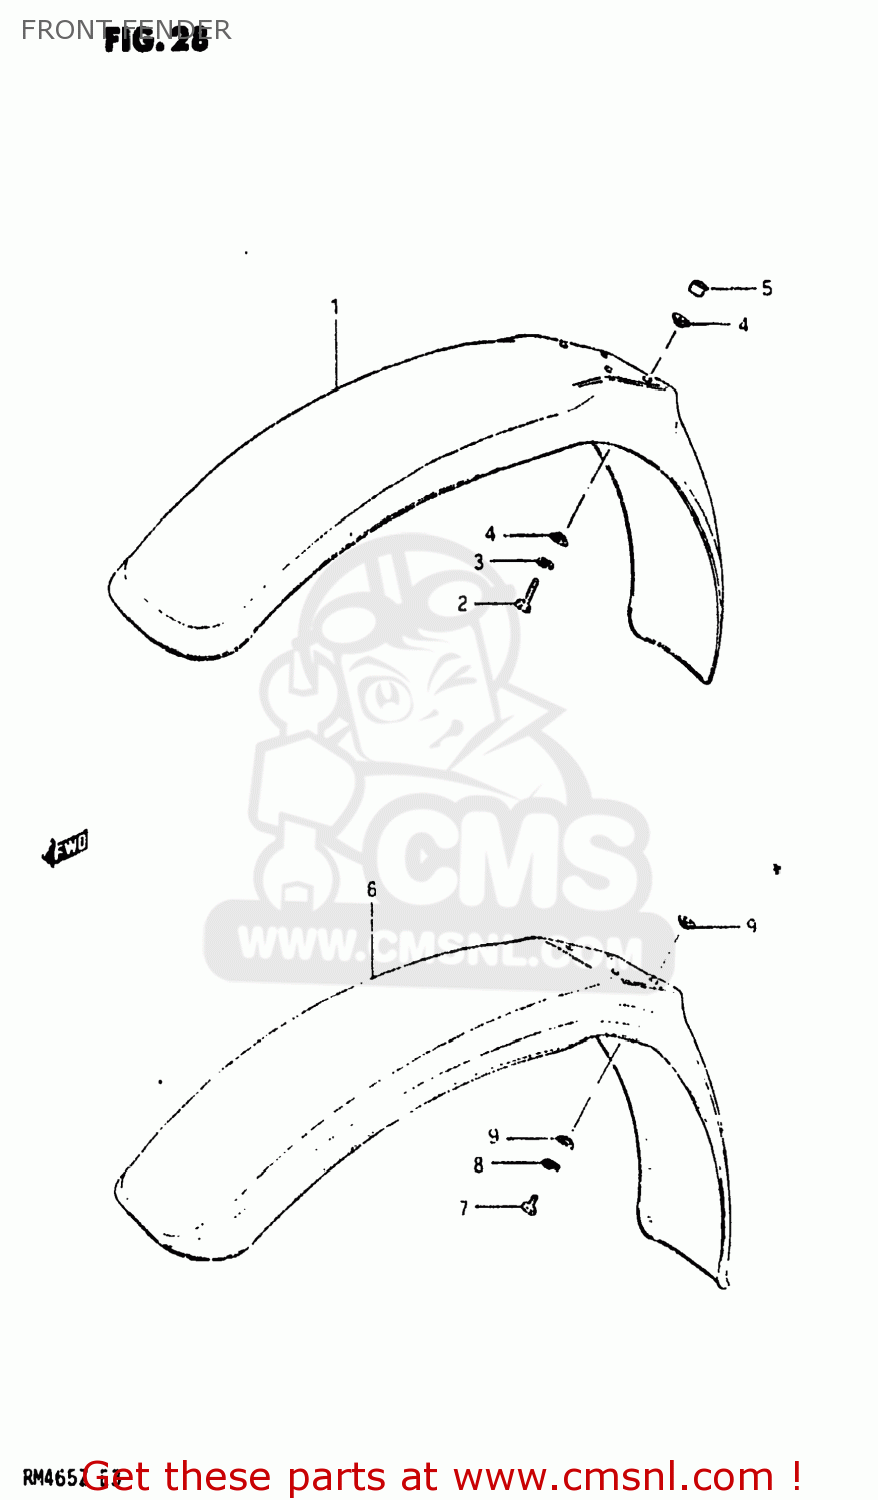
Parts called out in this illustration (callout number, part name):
1	FENDER,FRONT
2	BOLT
3	LOCK WASHER
4	WASHER
5	SPACER FRONT FENDER
6	FENDER,FR
7	BOLT, UPPER
8	LOCK WASHER
9	SPACER
